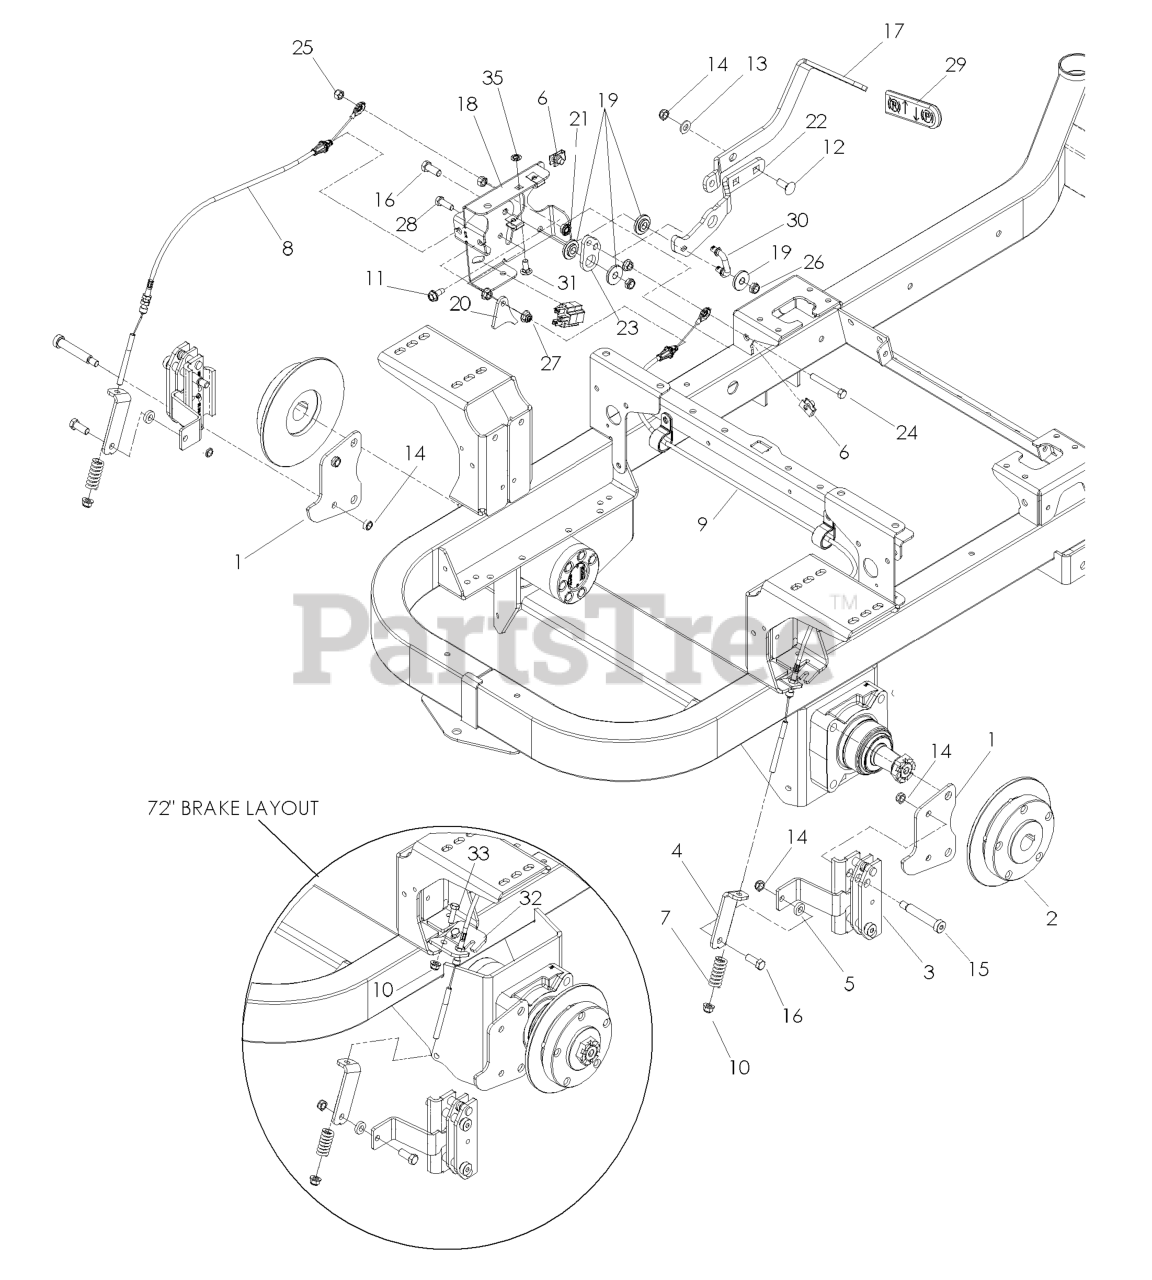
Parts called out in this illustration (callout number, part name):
1	PLATE, BRAKE
2	HUB, 5 BOLT
3	CALIPER PARK BRAKE
4	BRACKET, L
5	WASHER 3/8 X 3/4 X .187 TK
6	U-CLIP 5/16-18 NUT RETAINER
8	CABLE, BRAKE, SHORT
9	RP_CABLE, BRAKE, LONG
10	5/16-18 NYLOC FLANGE NUT
11	BOLT 5/16-18 X 3/4
12	RHSNB 3/8C X 1
13	WASHER 3/8 SAE FLAT
14	NUT HEX 3/8-16 NYLON, THIN
15	SB 3/8-16 X 2-1-1/2 SKT HDD ZD
16	HCS 3/8-16X1.GRD.5.ZD
17	ARM, BRAKE
18	MOUNT, BRAKE WLDMT
19	BUSHING, BRAKE
20	ACTUATOR, SWITCH
21	NUT 5/16C WHIZ
22	LEVER, BRAKE
23	BELLCRANK, BRAKE
24	HCS 5/16-18 X 2 1/2 TPBLT
25	NUT 5/16 NYLOC
26	NUT HEX 3/8-16 NYLON, THIN
27	5/16-18 NYLOC FLANGE NUT
28	HCS 5/16C X 1
29	GRIP, PARK BRAKE
30	LINKAGE, BRAKE
31	BOLT 5/16C X 3/4" CARRIAGE
32	BRKT, EXTENSION
33	HCS 5/16C X 1
